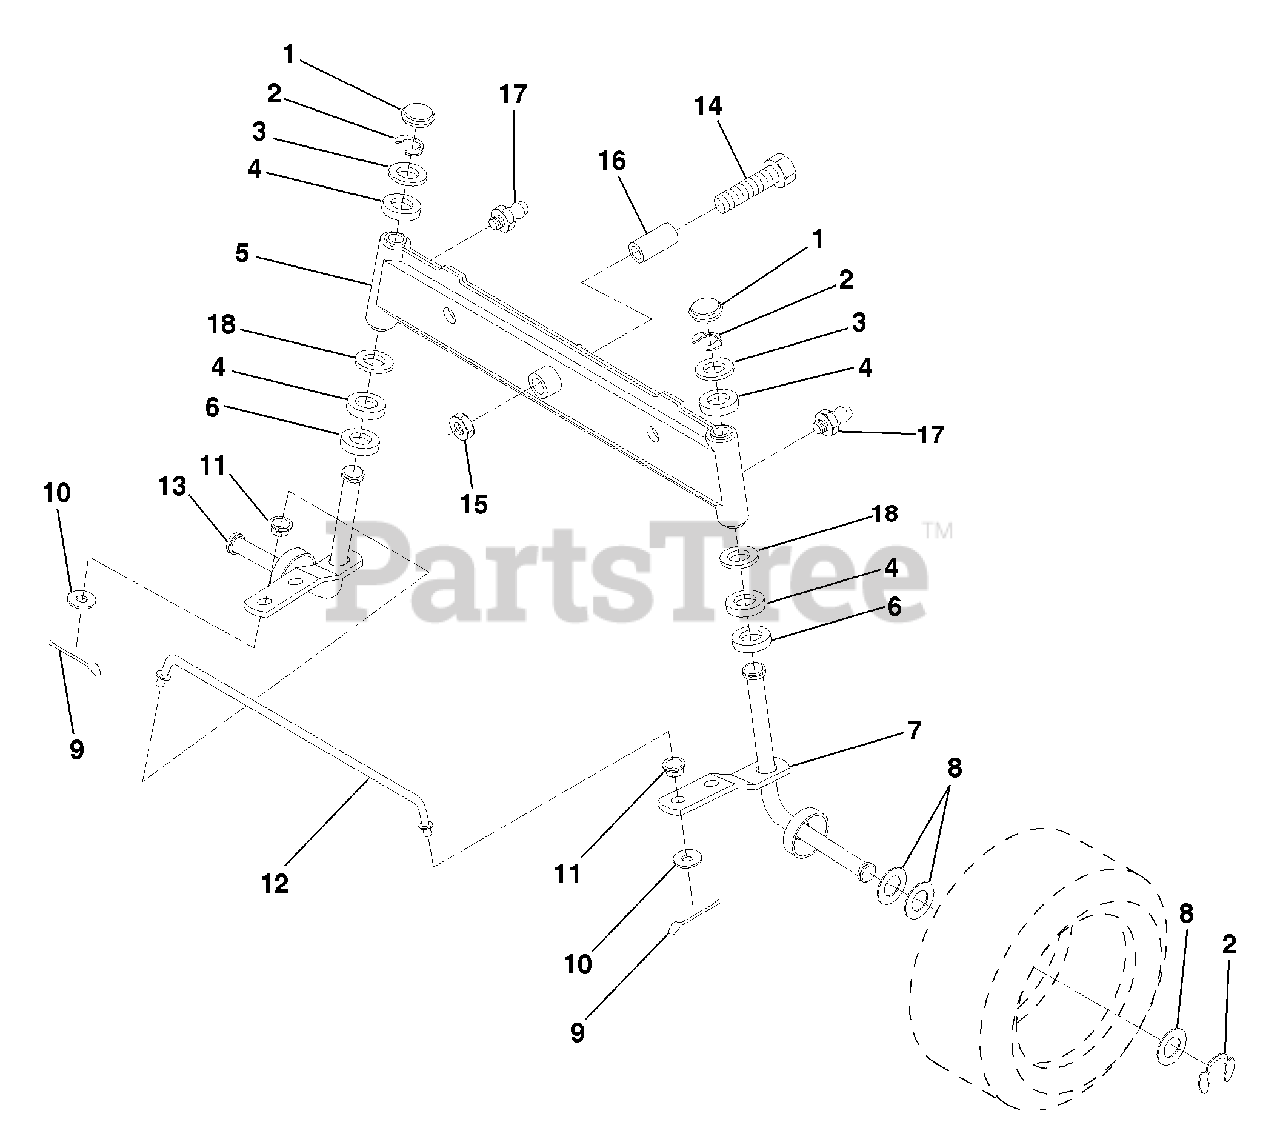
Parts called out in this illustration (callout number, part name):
1	Cap, Spindle
2	Ring, Clip
3	Washer 25/32 x 1-5/8 x 16 Ga.
4	Nyliner
5	Axle, Front
6	Bearing, Thrust
7	Spindle, R.H. Asm.
8	Washer 25/32 x 1-1/4 x 16 Ga.
9	Pin, Cotter 1/8 x 3/4
10	Washer 13/32 x 13/16 x 16 Ga.
12	Rod, Tie
13	Spindle, L.H. Asm.
14	Bolt Hex 5/1-11 x 3-1/2
15	Nut, Lock Flange 5/8-11
16	Spacer, Bearing Axle
17	Fitting, Grease
18	Washer 27/32 x 1-1/4 x 16 Ga.
